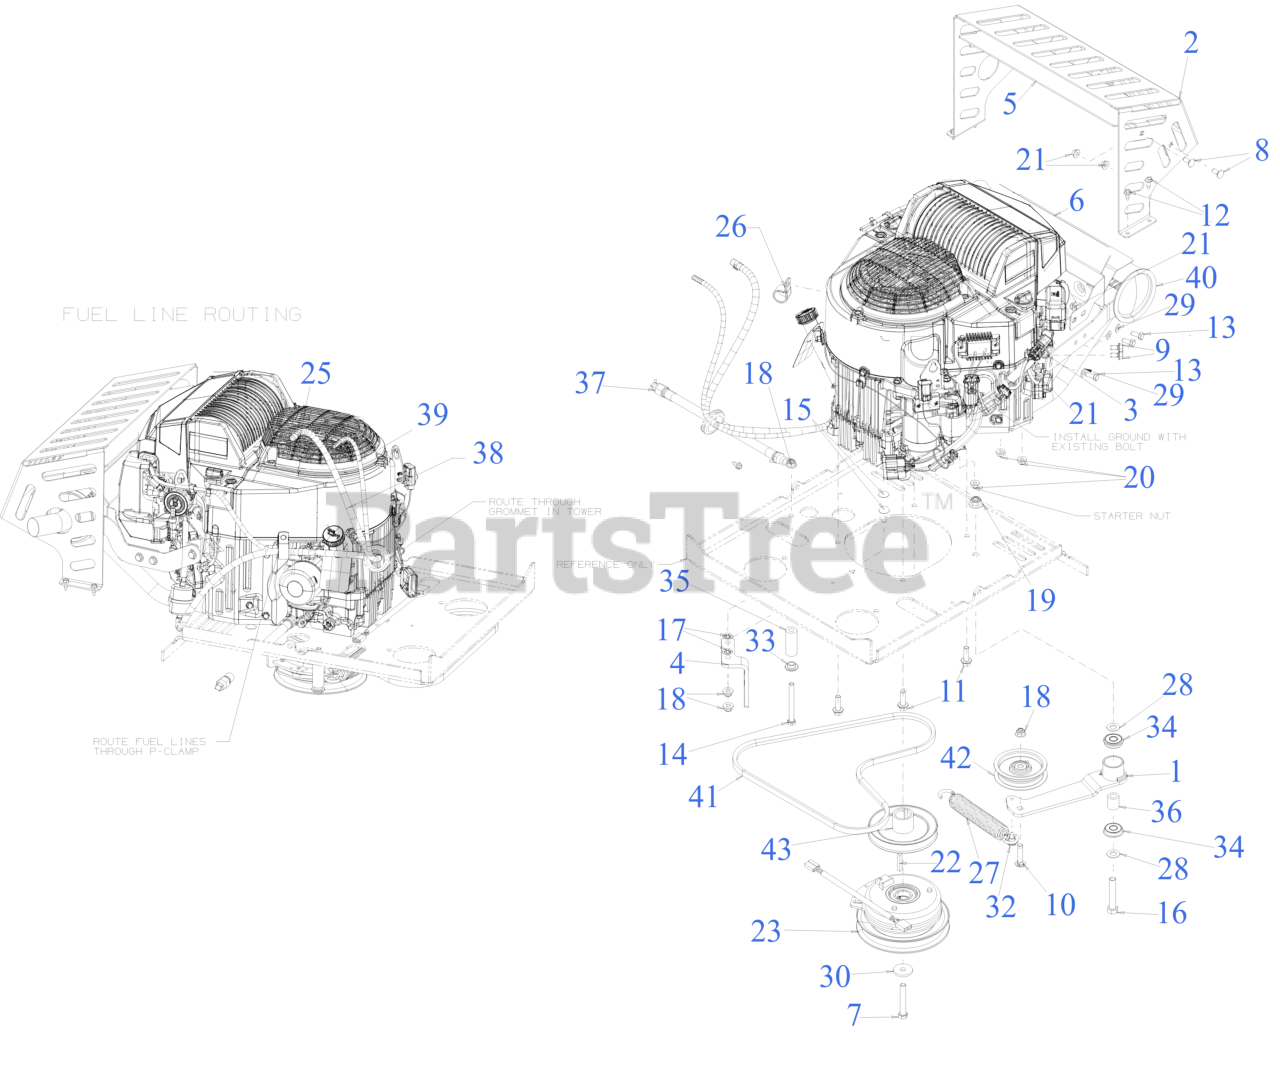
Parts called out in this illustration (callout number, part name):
1	IDLER BRACKET ASSEMBLY
2	MUFFLER SHIELD
3	MUFFLER MOUNTING BRACKET
4	CLUTCH BRACKET
5	MUFFLER SHEILD BRACKET (INNER)
6	MUFFLER SHIELD
7	SCREW 7/16-20:2.75 GR5
8	CARRIAGE BOLT 5/16-18 x .75
9	SCREW M8 x 1.25 x 16MM GR8.8
10	CARRIAGE BOLT 3/8-16 x 1.75 GR5
11	SCREW 3/8-16 x 1.25 GR5
12	SCREW 1/4-20X.625
13	SCREW 5/16-18 x .75 GR5
14	SCREW 3/8-16 x 3.50 GR5
15	CARRIAGE BOLT 3/8-16 x 1.00 GR5
16	SCREW 1/2-13 x 2.75 GR5
17	PUSH NUT
20	HEX FLANGE NUT
21	HEX FLANGE NUT
21	FLAT WASHER 1.0 OD:.331 ID
22	SQUARE KEY 1/4 x 1.50
23	ELECTRIC PTO CLUTCH
24	7" CABLE TIE
25	HOSE CLAMP 1/20
26	HOSE CLAMP 1.0"
27	SPRING 1.25" DIA x 8.5" LONG
28	FLAT WASHER .510 x .995
29	FLAT WASHER
30	FLAT WASHER .45 x 1.5 x .172 HT
32	SHOULDER SCREW .43X.29X5/16-18 TT
33	SHOULDER SPACER
34	ROLLER BEARING .5X1.37X.44
35	SPACER .41 x .875 x 2.19
36	SPACER 0.51 x 0.88 x 1.00
37	OIL DRAIN HOSE
38	FUEL HOSE LOW PERMEATION 36"
39	VENT HOSE 3/16 ID 45"LG
40	MUFFLER
41	BELT SEC A x 51.18
42	FLAT IDLER PULLEY 3.5
43	DRIVE PUMP PULLEY
